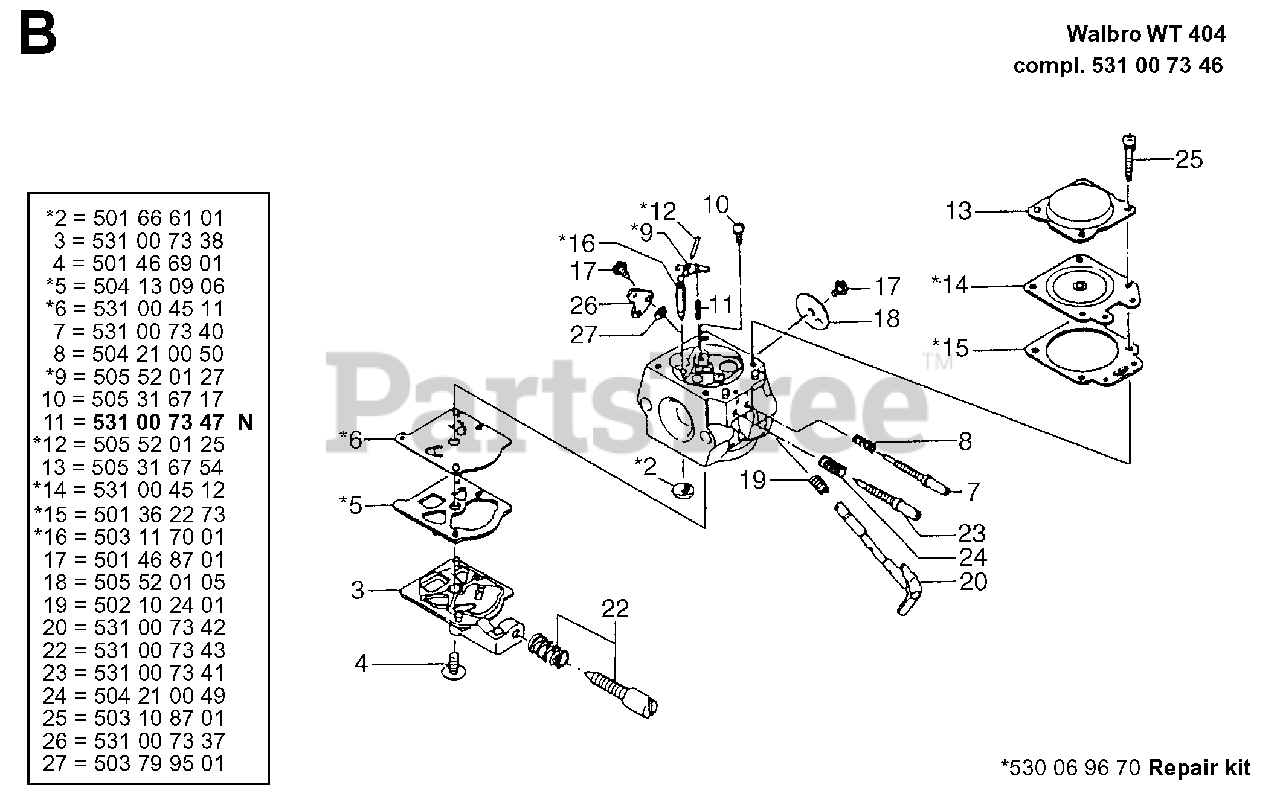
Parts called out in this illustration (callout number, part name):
2	FUEL INLET SCREEN
5	GASKET
7	NEEDLE HIGH SPEED
8	SPRING/COMPRESSION
9	LEVER
11	SPRING
12	FULCRUM PIN
13	DIAPHRAGM COVER
15	GASKET
16	VALVE/INLET.
18	THROTTLE FLAP
19	SPRING, CARB. 40
20	THROTTLE SHAFT
22	IDLE SCREW
23	LOW SPEED NEEDLE
24	SPRING, H-NEEDLE
25	SCREW W/ WASHER
